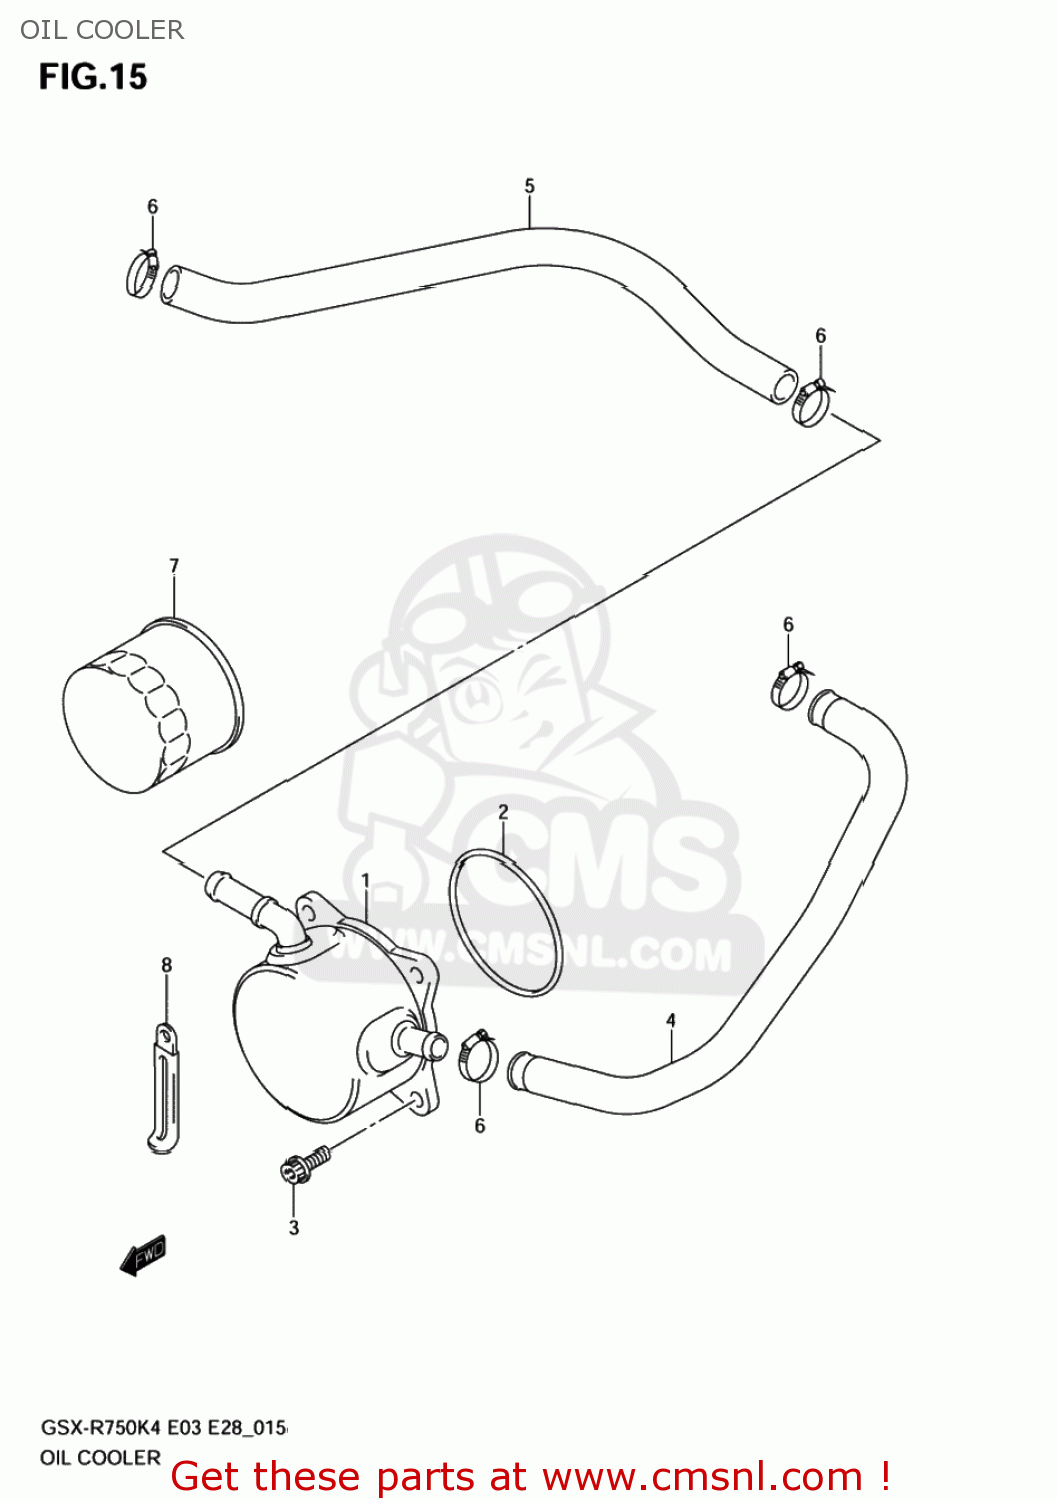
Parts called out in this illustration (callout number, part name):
1	COOLER ASSY,OIL
2	O RING(D:3.1,ID:63.9)
3	BOLT(6X16)
4	HOSE,OIL COOLER WATER INLET
5	HOSE,OIL COOLER WATER OUTLET
6	CLAMP
7	FILTER ASSY,EN
8	CLAMP(L:80)
